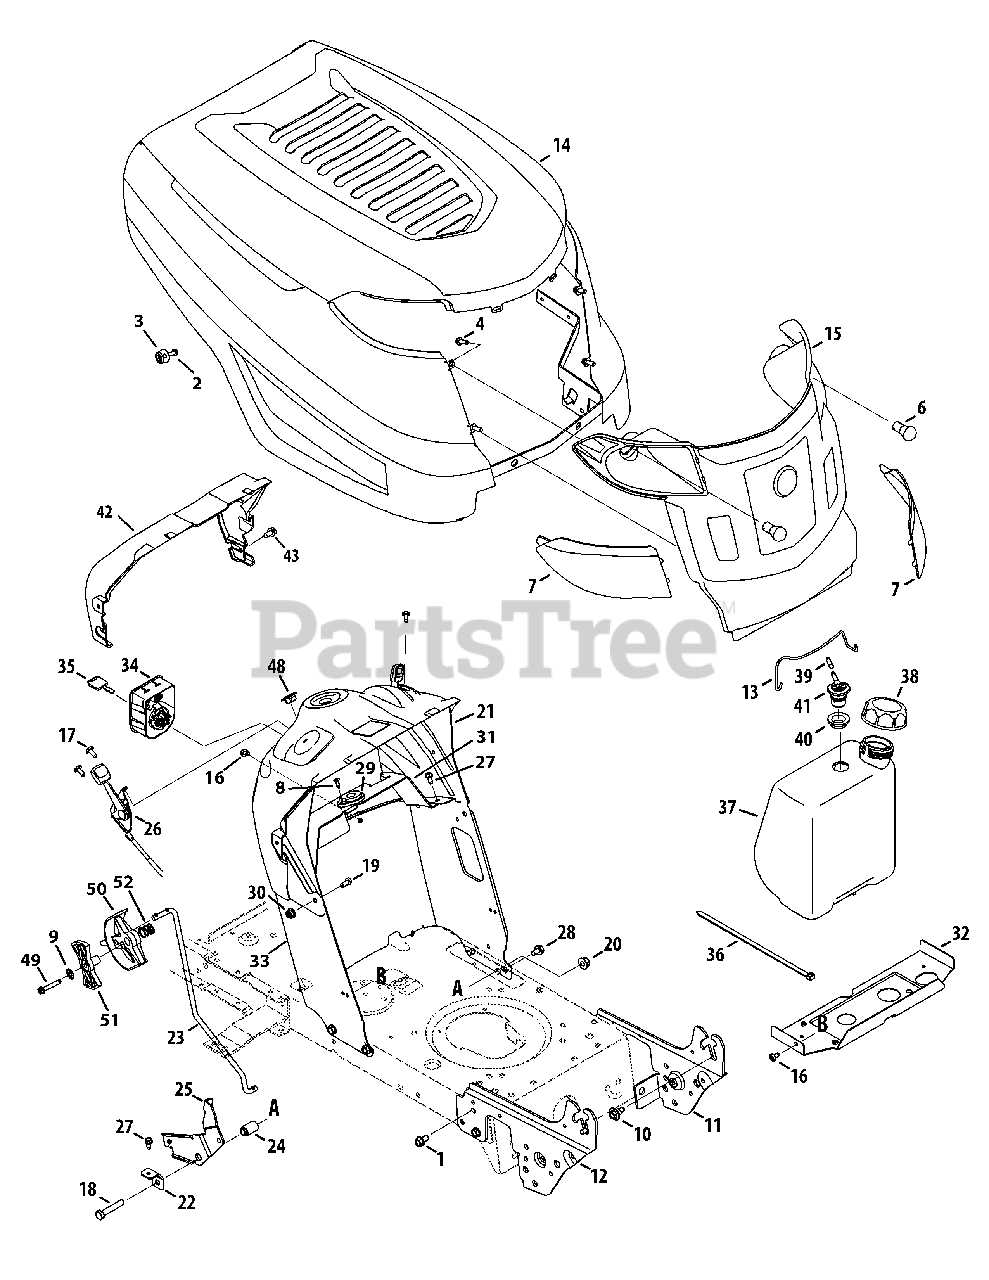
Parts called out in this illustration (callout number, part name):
1	Screw 5/16-18 x .75
2	Screw #12-16 x 1.25
3	K-Style Bumper
4	Screw 1/4 x .750
5	Cable Tie
6	Miniature Lamp 12V Socket
7	Grill Lens - LH
7	Grill Lens - RH
8	Screw, #10-16 x .50
9	Lockwasher 1/4ID
10	Shoulder Screw 5/16-18 x .43 x .29
11	Left Support Pivot Bracket
12	Right Support Pivot Bracket
13	Battery Rod
15	Grille Ass’y
16	Self-Tapp Screw 1/4-20 x .50
17	Self-Tapp Screw 1/4-20 x .50
18	Hex Screw 3/8-16 x 2.0 Gr. 5
19	Screw 5/16-18 x .625
20	Hex L-Flg. Nut 3/8-16 Gr. F, Nylon
21	Upper Dash
22	Speed Latch
23	Speed Selector Control Rod
24	Flange Spacer
25	Transmission Speed Latch
26	Tap Screw 1/4-20 x 0.625
28	Screw 5/16-18 x .675
29	Bearing .628 ID x 1.36
30	Flange Locknut 5/16-18 Gr. F, Nylon
31	Steering Support Bracket
32	Gas Tank Support Bracket
33	Dash, Lower
34	3 Position Key Switch
36	Cable Tie
37	Fuel Tank 1.36 gal.
38	Cap-Fuel
39	Hose Vent
40	Rubber Grommet
41	Rollover Valve
43	Hi-Lo Screw 1/4-15 x .75
44	Choke Plug
45	Hex Washer Scr. 1/4-20 x 1.50
46	Shift Lever
47	Index Control
48	Compression Spring .685 OD x .63
